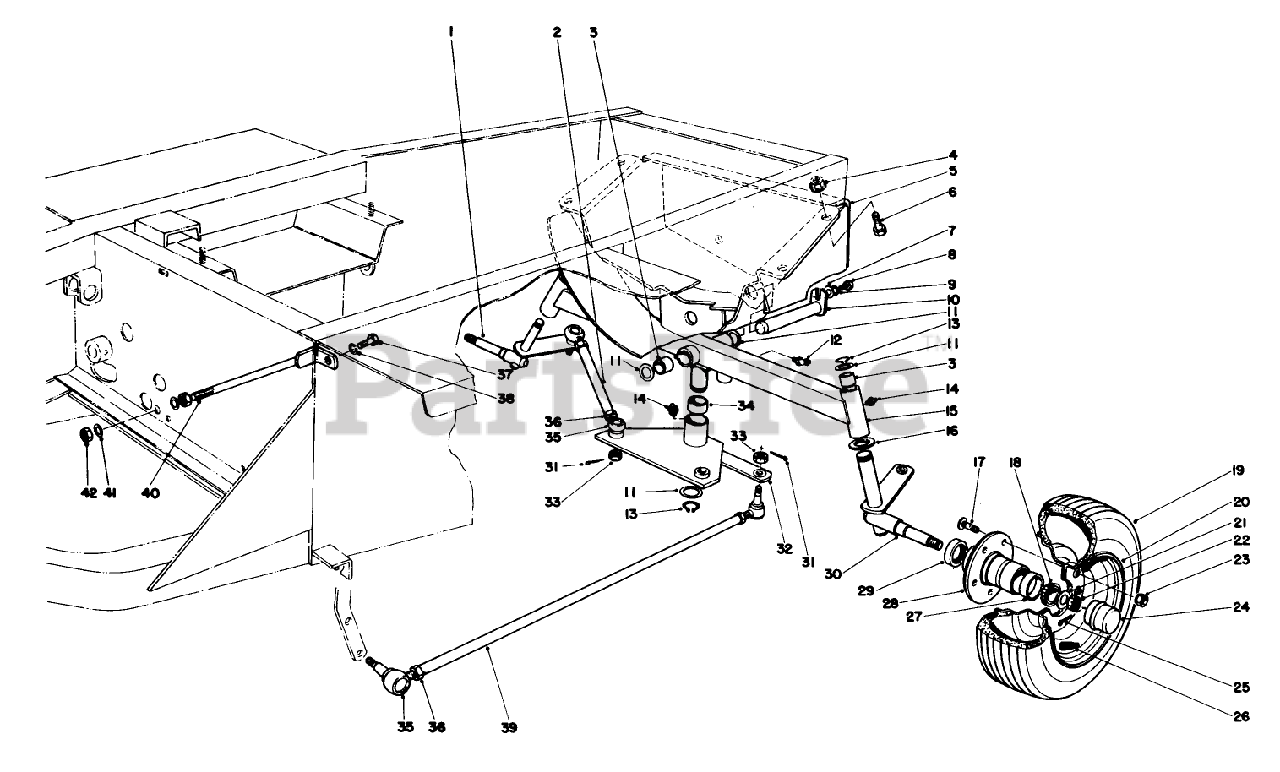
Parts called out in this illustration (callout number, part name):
1	Spindle Assembly R.H.
2	TIE ROD-STEERING
3	BUSHING
4	NUT-HF
5	AXLE SUPT WA R
6	SCREW-HHF
7	WASHER-PLAIN
8	SCREW-HH
9	WASHER-LOCK
10	REAR AXLE PIN WA R
11	SPACER
12	FITTING-LUBE, 45 DEG
13	RING-RETAINING
14	FITTING-GREASE
15	Rear Axle (Incl. Ref. #3)
16	WASHER-THRUST
17	STUD-TYPE, DRIVE
18	BEARING-CONE, TAPERED
19	TIRE-Ribbed
20	WHEEL-8 INCH
21	WASHER-FLAT
22	NUT-HEX, SLOTTED
23	NUT-LUG
24	CAP-DUST
25	PIN-COTTER
26	STEM-VALVE
27	BEARING-CUP, TAPERED
28	Hub-Wheel (Incl. Ref. #17 & 27)
30	Spindle Assembly L.H.
31	PIN-COTTER
32	Rear Steering Pivot (Incl. Ref. #34)
33	NUT-SLOTTED
34	BUSHING
35	Socket Assembly R.H. Thread (Incl. Ref. #33)
36	NUT-JAM
37	SCREW-HH
38	WASHER-LOCK
39	REAR STRG TUBE PP
40	Axle Support
41	WASHER-FLAT
42	NUT-HH
